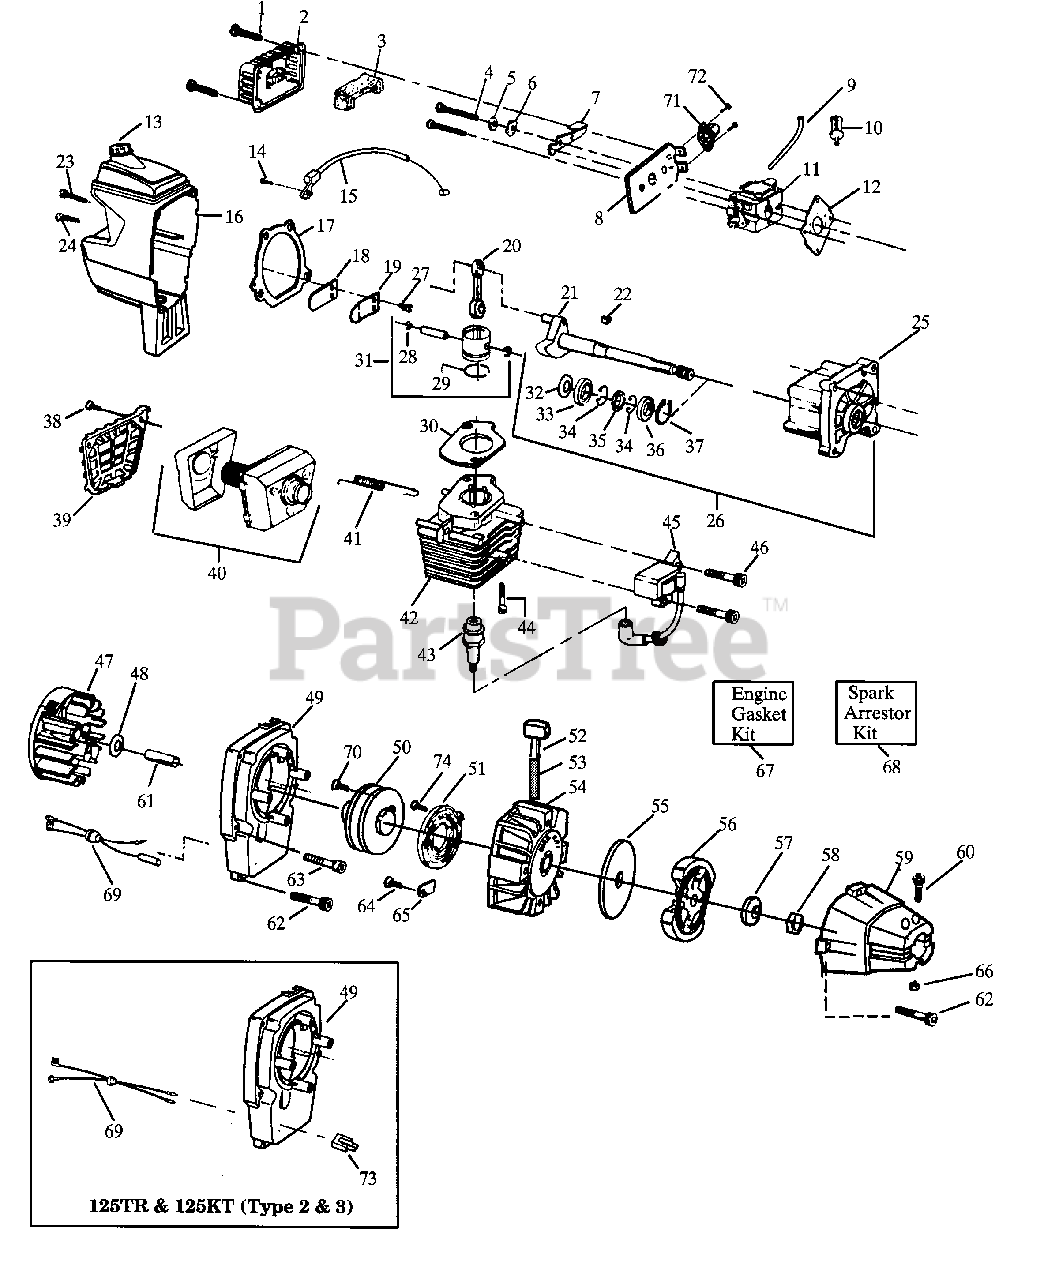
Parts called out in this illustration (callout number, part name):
2	Air Filter Cover
3	Air Filter
6	Wave Washer
7	Choke Shutter
8	Type 1 Model XT125, XT125T,XT125KT
8	Type 1-2 Model XT125TR & Type 2-3 XT125KT
9	Fuel Line
9	Return Line Types 2 & 3 Model XT125TR,XT125KT
10	Fuel Pick-up Ass'y.
11	Type 1 (WA-199) Model XT125, XT125T,XT125KT
11	Type 1-2 Model XT125TR
11	Type 2-3 (WT-298A) Model XT125KT
12	Carburetor Gasket
13	Fuel Cap Ass'y.
15	Type 1 & 2 XT125,XT125T
15	Type 1 Model XT125K,XT125KT
15	Type 1-2 Model XT125TR
15	Type 2-3 Model XT125KT
16	Type 1 Model XT125,XT125T,XT125KT
16	Type 1-2 Model XT125TR
16	Type 2-3 Model XT125KT
19	Reed Stop
20	Connecting Rod Ass'y. (Inc.Bearings)
21	Crankshaft Ass'y. See Service Ref. 1
22	Flywheel Key
25	Crankcase Ass'y. (Inc.33-36)
26	Crankcase & Crankshaft Ass'y. (Inc.21,25, 33-37)
28	Piston Pin Retainer
29	Piston Ring
30	Cylinder Gasket
31	Piston Kit (Inc.28,29 & pin)
33	Inner Bearing
34	Retaining Ring
35	Crankshaft Seal
36	Outer Bearing
37	Crankshaft Retaining Ring
39	Muffler Guard
40	Muffler Kit
41	Muffler Spring
42	Cylinder
43	Type 1 & 2 Model XT125,XT125T,XT125K,XT125KT
43	Type 1 Model XT125TR
43	Type 2 Model XT125TR
43	Type 2-3 Model XT125KT
45	Ignition Module Kit
46	Screw
47	Flywheel Ass'y.
48	Washer
49	Fan Housing
50	Starter Pulley Kit (Inc.70)
51	Starter Spring
52	Starter Handle
53	Rope Kit
54	Pulley Housing Ass'y.
55	Clutch Washer
56	Clutch Ass'y. Kit
59	Clutch Housing
65	Pulley Retainer
67	Engine Gasket Kit (Inc.12,17,30)
68	Spark Arrestor Kit
69	Type 1 Model XT125,XT125T,XT125K,XT125KT
69	Type 1-2 Model XT125TR
69	Type 2-3 Model XT125KT
70	Screw-Pulley
71	Primer Bulb Ass'y. Type 1-2 Model XT125TR
71	Type 2-3 Model XT125KT
72	Screw-Primer Type 1-2 Model XT125TR
72	Type 2-3 Model XT125KT
73	Connector Type 1-2 Model XT125TR
73	Type 2-3 Model XT125KT
74	Screw-Starter Spring Type 2 Model XT125TR
74	Type 3 Model XT125KT
74	, Instruction Decal
